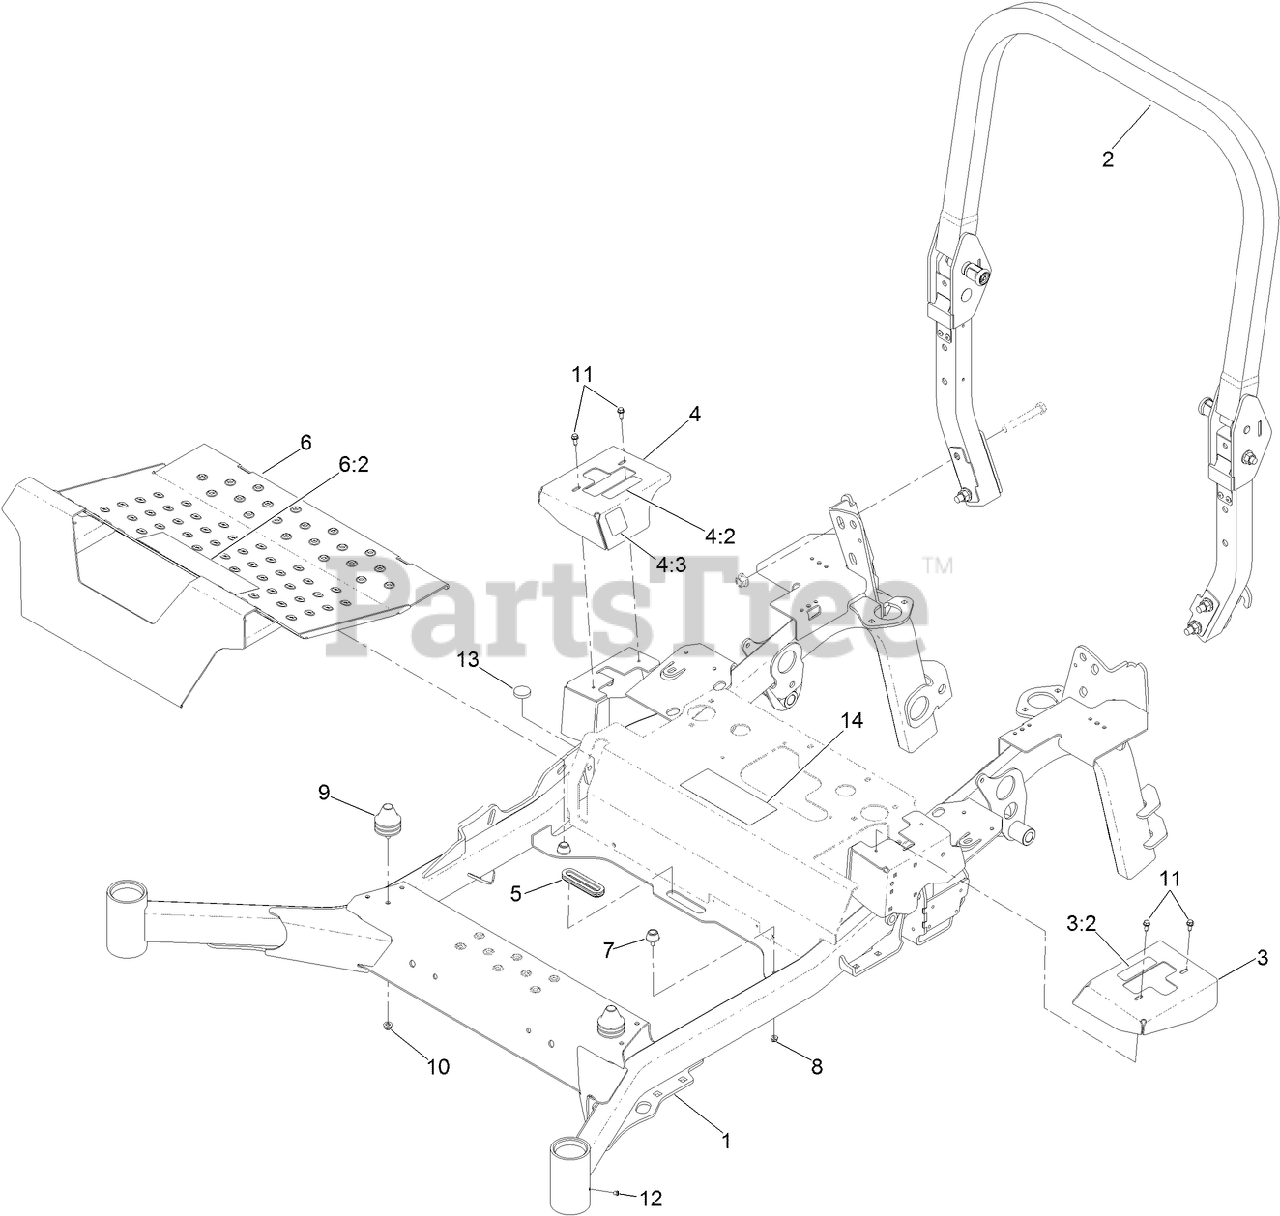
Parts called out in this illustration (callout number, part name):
1	FRAME
2	ROPS ASM
3	COVER-MOTION CONTROL, LH
3:2	DECAL-CONTROL, MOTION
4	COVER-MOTION CONTROL, RH
4:2	DECAL-CONTROL, MOTION
4:3	DECAL-PARK BRAKE, CE
5	GROMMET-RUBBER
6	PAN-FLOOR
6:2	DECAL-DANGER
7	BUMPER-RUBBER
8	NUT-HF
9	ISOLATOR
10	NUT-HF, NI
11	SCREW-HWH
13	BUMPER-PUSH-IN, RUBBER
14	DECAL-SERVICE AID
